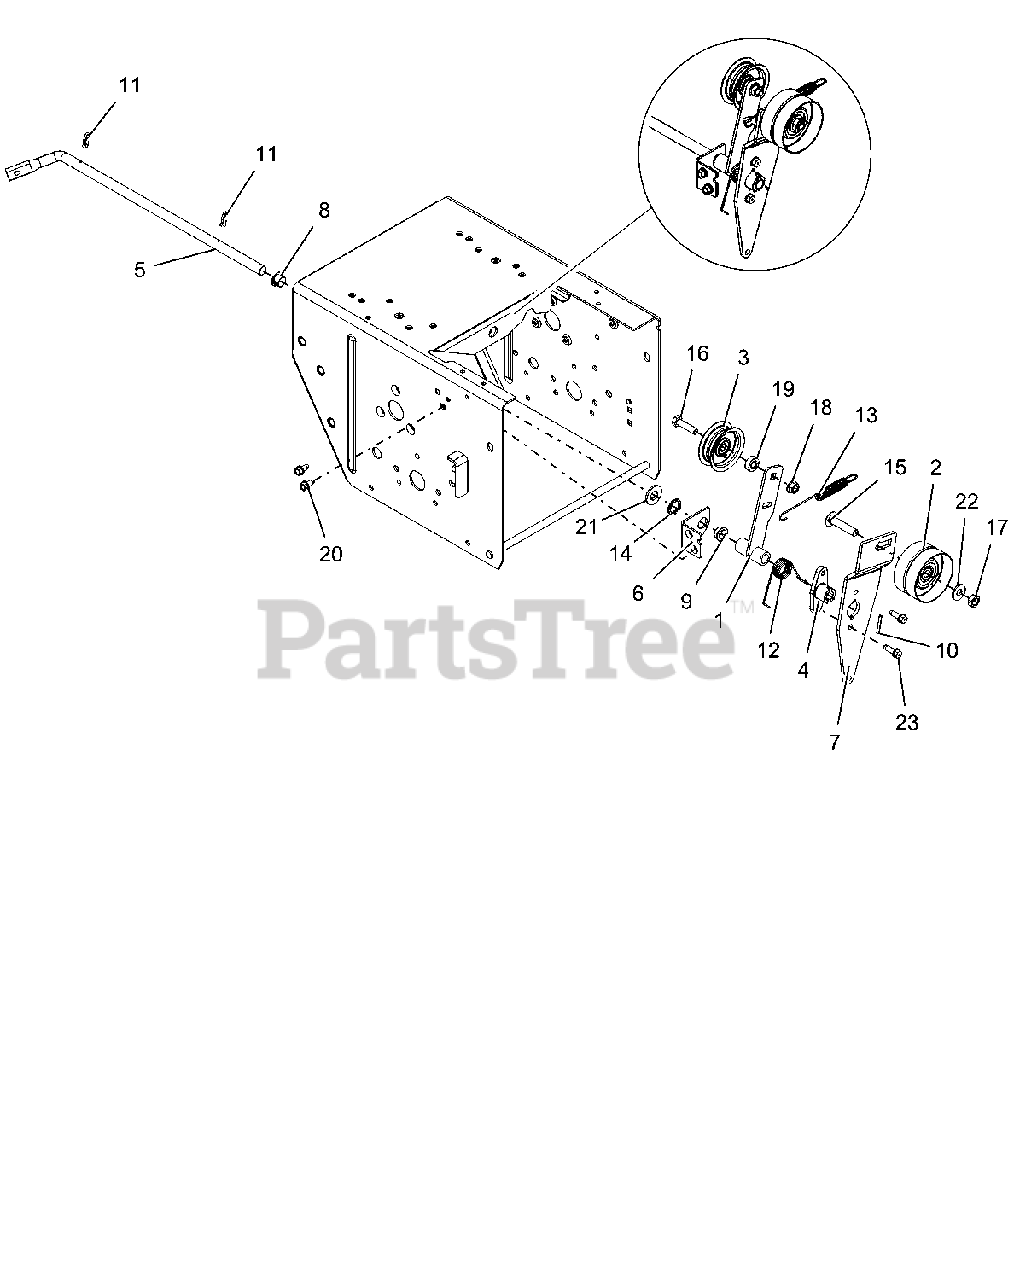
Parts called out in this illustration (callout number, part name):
1	ARM, IDLER-TRACTION
2	IDLER, FLAT-2.75 OD X .375 ID
3	IDLER, FLAT - 2.00"
4	HUB, BRAKE ARM
5	ARM, ATTACHMENT
6	BRACKET, SUPPORT
7	ARM, IDLER-ATTACHMENT
8	BUSHING, POLYLINER-.50 SPLIT
9	BSHG,FLANGE .500X.625X.270X.75
10	PIN-ROLL .125X1.00
11	CLIP, SPRING
12	SG-TORS .067X.88
13	SG-TENS .06X.482X5.35
14	WAVE SPRING .600X.875X.25FH
15	BLT-RHDSSQNK .38-16X1.75 G5YZ
16	BLT-HEX .31-18X1.25 GR5 YWZC
17	NUT-LK-CTR-JAM .375-16 YWZC
18	NUT-LK-TOP-FLG .31-18 YWZC
19	SPCR, BRG .315X.500X.358X.281
20	SCR-TAP .25-20X.50 HWH TR YWZ
21	WSHR-FL-STL.531X1.06X.095YWZC
22	WSHR-FL-STL.38X.875X.083 YWZC
23	SCR-TAP-PM .25-20X.75 TR YWZ
